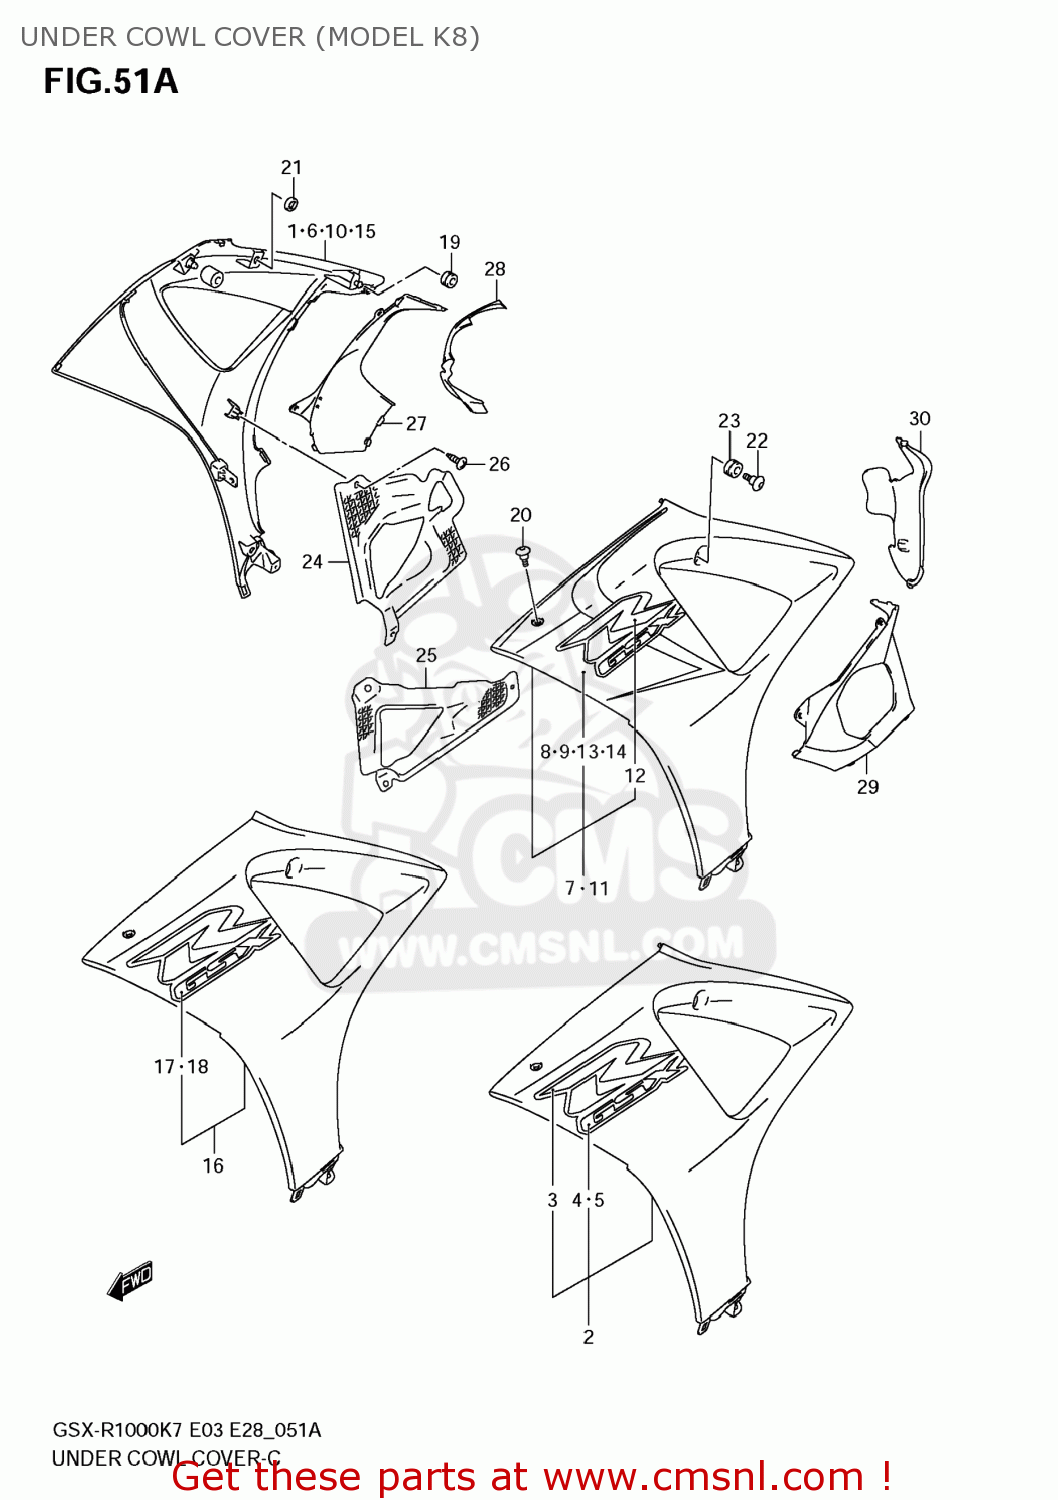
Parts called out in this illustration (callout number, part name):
1	COVER,UNDER COWL,R(BLACK)
2	COVER,UNDER COWL,L(BLACK)
3	EMBLEM,R
4	EMBLEM,GSXR,R
5	EMBLEM,GSXR,L
6	COVER,UNDER COWL,R(WHITE)
7	COVER,UNDER COWL,L(WHITE)
8	TAPE,COVER UNDER COWL SIDE,R
9	TAPE,COVER UNDER COWL SIDE,L
10	COVER,UNDER COWL,R(GRAY)
11	COVER,UNDER COWL,L(GRAY)
12	EMBLEM,R
13	TAPE,COVER UNDER COWL SIDE,R
14	TAPE,COVER UNDER COWL SIDE,L
15	COVER,UNDER COWL,R(BLUE)
16	COVER,UNDER COWL,L(BLUE)
17	EMBLEM,R
18	EMBLEM,L
19	CUSHION
20	SCREW(5X13)
21	CUSHION
22	SCREW(6X20)
23	CUSHION
24	SHIELD,UNDER COWL HEAT,R
25	SHIELD,UNDER COWL HEAT,L
26	SCREW
27	COVER,UNDER COWL LWR,R
28	PROTECTOR,COWLING UNDER
29	COVER,UNDER COWL LWR,L
30	PROTECTOR,COWLING UNDER
